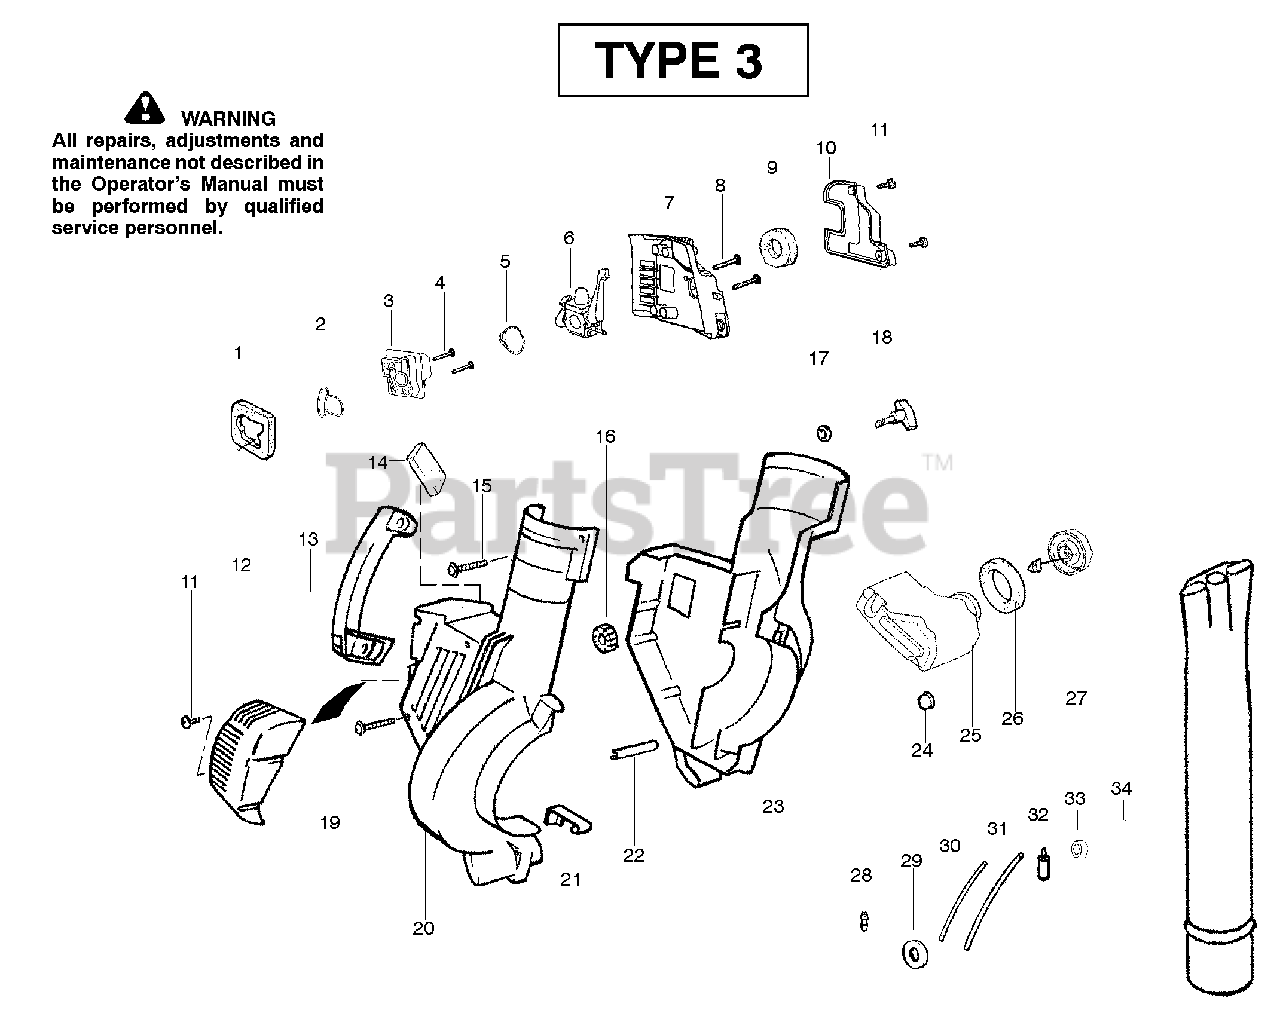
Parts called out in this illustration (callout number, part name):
1	Air Dam (kit)
2	Gasket-Adapter (kit)
3	Carburetor Adaptor
5	Gasket-Carburetor (kit)
6	Kit-Carb Ass'y. Zama-(C1Q-W11C)
6	Kit-Carb Ass'y. Walbro-(WT-784)
8	Screw-Carb.
9	Filter-Air
10	Cover-Air Filter
12	Guard-Muffler
14	Foam - 71.12mm (kit)
16	Isolator
18	Knob-Tube Clamp
19	Reflector-Heat (kit)
20	Assy-Shroud RH
21	Spring-Cover Latch
22	Guide-Starter Rope
23	Shroud - LH
24	Isolator-Crankcase
25	Assy-Fuel Tank
26	Gasket-Fuel Tank
27	Fuel Cap w/Retainer
28	Fitting-Fuel Line
29	Grommet-Shroud
30	Kit-Line Carb/Purge
31	Kit-Line Tank/Purge
32	Assy-Fuel Pick-up
33	Grommet-Fuel line (kit)
34	Tube-Blower
